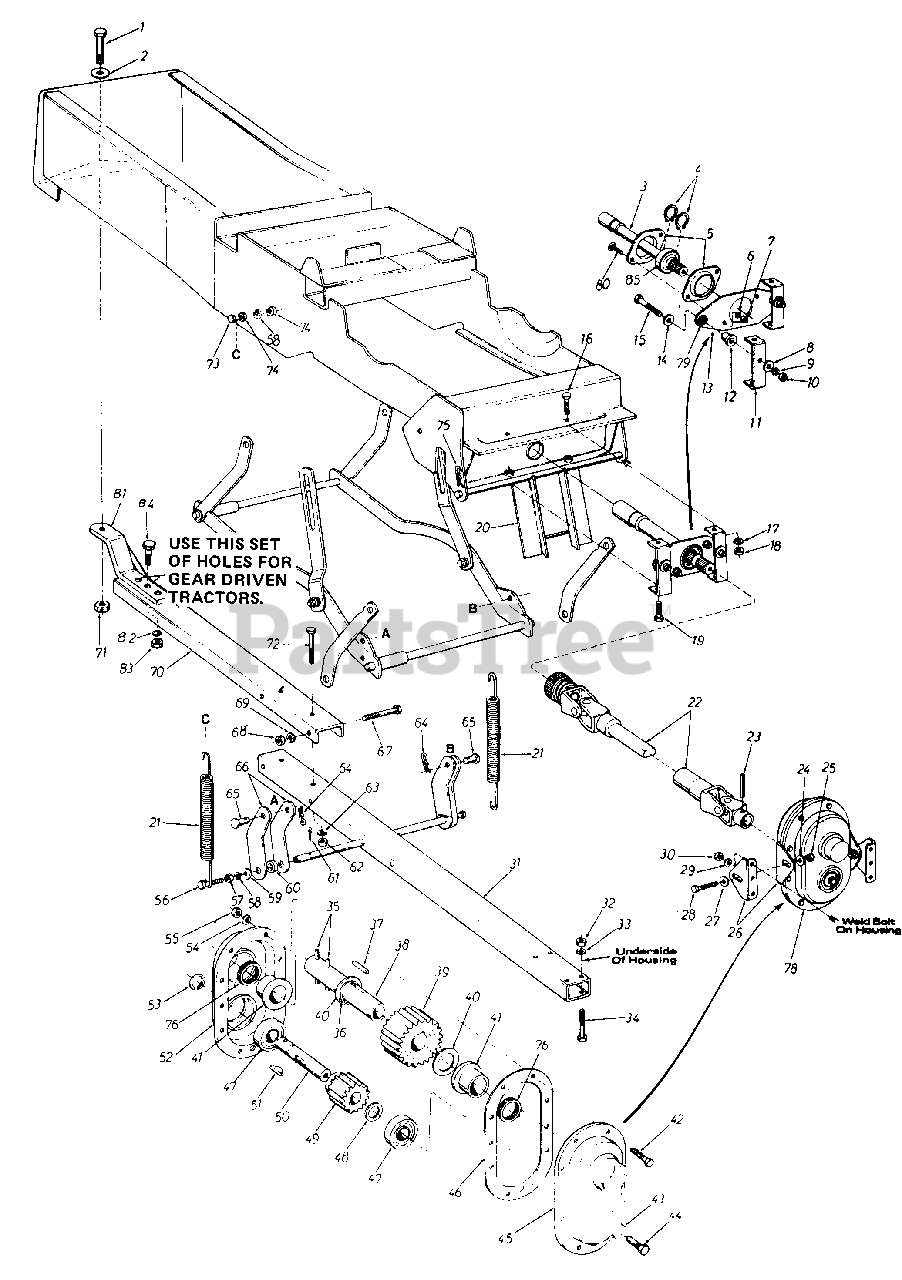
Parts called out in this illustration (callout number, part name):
1	Hex Scr. 5/8 18 x 1.31"Lg.
2	Fl.-Wash. .66" I.D x 1.25" O.D. x .100
3	P.T.O. Shaft Extension Ass'y.
4	Retaining Ring 1.00" Dia. Shaft
5	Flangette Bearing
6	L.-Wash. 5/16" Scr.
7	Hex Nut 5/16-18 Thd.
8	Fl.-Wash. 3/8" I.D. x 1.00" 0.D.
9	L. Wash 3/8" Scr.
10	Hex Nut 3/8 24 Thd.
11	P.T.O. Bearing Retain Brkt.
12	Shoulder Spacer
13	P.T.O. Bearing Retainr Plate
14	Fl.-Wash. 3/8" I.D. x 1.00 O.D.
15	Hex Scr. 3/8-24 x 1.50"
16	Hex Scr. 3/8-16 x .75"
17	L.-Wash. 3/8" Scr.
18	Hex Nut 3/8-16 Thd.
19	Hex Scr. 3/8-16 x .75" Lg.
20	Guide Bracket Ass'y.
21	Helper Spring .94 O.D. x 7.38" Lg.
22	Universal Drive Shaft Ass'y.
23	Spring Pin Spirol 5/16" x 2.50" Lg.
24	Belleville Wash. .341 I.D. x .88 O.D.
25	Hex Nut 5/16-18 Thd.
26	Gear Box Support Bracket
27	Belleville Wash. .34 I.D. x .88 O.D.
28	Hex Scr. 5/16-18 x .75" L.g
29	L.-Wash. 5/16" Scr.
30	Hex Nut 5/16-18 Thd.
31	Lift Shaft Ass'y.
32	Hex Ins. Jam L.-Nut3/8-24 Thd.
33	L.-Wash. 3/8" Scr.
34	Hex Scr. 3/8-24 x 2.75"Lg.
35	Spring Pin Spirol 5/16" Dia. 1.75" Lg.
36	Snap Ring for 1.25" Dia. Shaft
37	Sq. Key 1/4" x 1.00" Lg.
38	Gear Shaft
39	28 Teeth Spur Gear
40	Fl.-Wash. 1.31" I.D x 2.00" O.D. x .060
41	Flange Bearing 1.25" I.D. x 1.75" O.D.
42	Hex Screw 1/4 28 x 88 "Lg.
43	Fl.-Wash. .40" I.D. x 1.25" O.D. x 160
44	Hex L.-Scr. 3/8-24 x 1.00" Lg.
45	Complete Gear Housing Half-L.H.
46	Gasket
47	Bal Bearing 1.00" I.D. x 2.00" O.D.
48	Fl.-Wash. 1.03" I.D. x 1.63" O.D. x .090
49	15 Teeth Spur Gear
50	Input Shaft
51	Woodruff Key 1/4 x 3/4" Dia.
52	Complete Gear Housing Half-R H
53	Snap Ring for 1.00" Dia. Shaft
54	L.-Wash. 1/4" Scr.
55	Hex Nut 1/4-28 Thd.
56	Hex Scr: 5/16-18 x 1.75" Lg.
57	Hex Nut 5/16-18 Thd.
58	L.-Wash. 5/16" Scr.
59	Fl.-Wash. .344 I.D. x 1.12 O.D. x .125
60	Spacer .81" I.D. x 1.00" O.D. x .31
61	Cotter Pin.5/32" Dia. x 1.00" Lg.
62	Hex Ins.Jam L.-Nut 3/8-24 Thd.
63	L.-Wash. 3/8" Scr.
64	Intern. Cotter Pin 1/2" Dia.
65	Clevis Pin .500" Dia.
66	Lift Bracket
67	Hex Scr. 3/8-24 x 4.50" Lg.
68	Hex Ins.Jam L.-Nut 3/8-24 Thd.
69	L.-Wash. 3/8" Scr.
70	Lift Bracket
71	Hex Ins. Jam L.-Nut 5/8-18 Thd.
72	Hex Scr. 3/8-24 x 2.75" Lg
73	Hex Scr. 5/16-18 x 1.75 Lg.
74	Hex Nut 5/16-18 Thd.
75	Intern. Cotter Pin 3/4"Dia.
76	Oil Seal 1.25" I.D. x 1.75" O.D. x .26
78	Gear Box Ass'y. Comp.
79	Rubber Grommet .50" I.D.
80	Carriage Bolt 5/16-18 x .75" Lg.
83	Hex Nut 1/2-13 Thd.
84	Hex Scr. 1/2-13 1-1/4 Lg.
85	Ball Bearing
